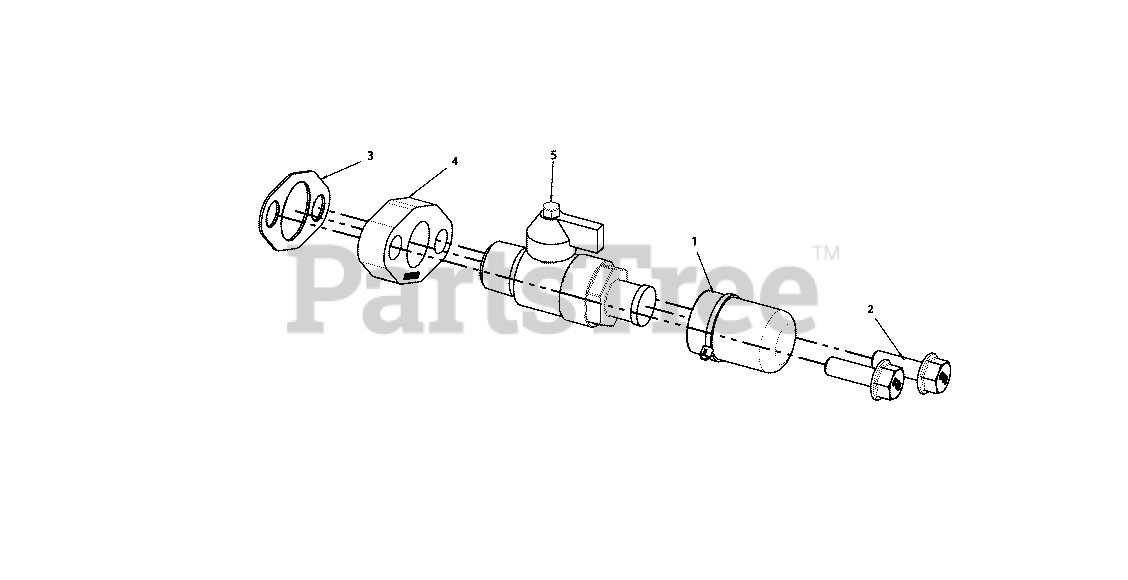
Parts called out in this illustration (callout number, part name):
1	RUBBER CAP
2	* BOLT
3	GASKET
4	* PLATE
5	VALVE
